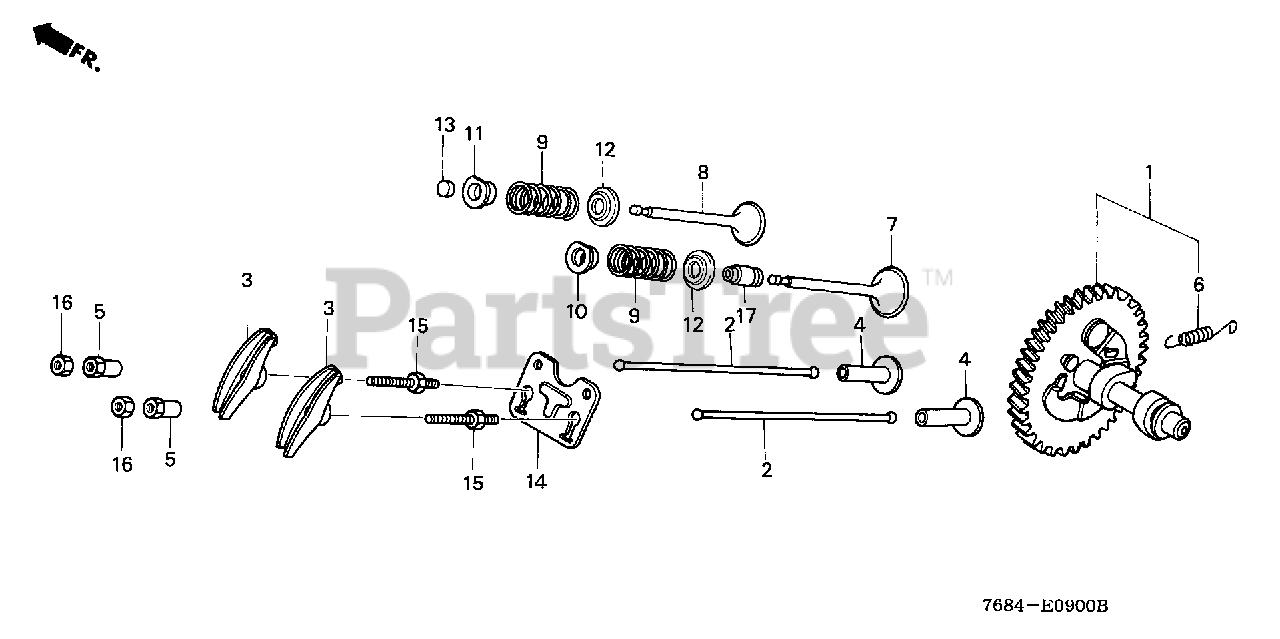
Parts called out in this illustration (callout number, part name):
1	CAMSHAFT ASSY.
3	ARM, VALVE ROCKER
4	LIFTER, VALVE
5	PIVOT, ROCKER ARM
6	SPRING, WEIGHT RETURN
7	VALVE, IN.
8	VALVE, EX.
9	SPRING, VALVE
10	RETAINER, IN. VALVE SPRING
11	RETAINER, EX. VALVE SPRING
12	SEAT, VALVE SPRING
13	ROTATOR, VALVE
14	GUIDE, PUSH ROD
15	BOLT, PIVOT (8MM)
16	NUT, PIVOT ADJUSTING
17	SEAL, VALVE STEM
